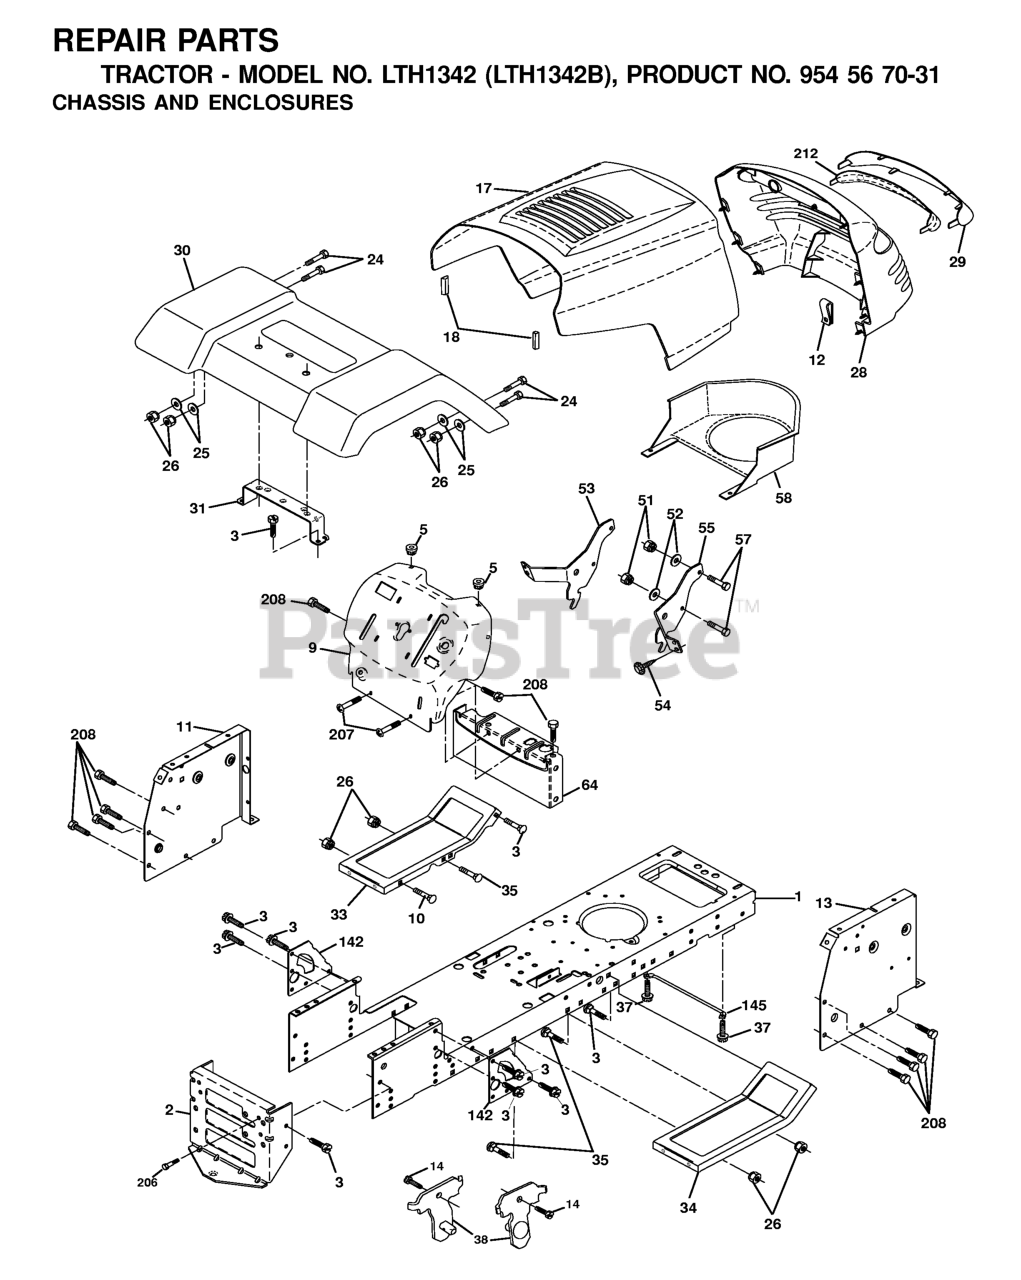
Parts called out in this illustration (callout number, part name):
1	CHASSIS STAMPING
2	DRAWBAR, 12GA
3	SCREW 3/8-16X3/4
5	BUMPER.RUBBER.HOOD
9	DASH
10	BOLT D
11	PANEL DASH LH
13	PANEL DASH RH
17	HOOD ASM.
18	BUMPER HOOD T
25	WASHER
26	NUT
28	GRILLE/LENS ASM.
29	LENS P/L
30	FENDER
31	BRACKET FENDER
33	FOOT REST LH
34	FOOTREST RH
37	Screw 5/16-18 x 1/2 Hex, Self Tapping 5/16-18 x 1/2
38	BRACKET
51	LOCKNUT.NYLOC.1/4-20
53	BRACKET.GRILLE.LH
54	SCREW.HEX.WS.HD.8-18 X 7/8
57	BOLT
58	AIR DUCT P/L/LT
64	DASH LOWER
142	PLATE
145	ROD PIVOT CHASSIS/HOOD
206	SHOULDER BOLT 5/16-18TT
207	SCREW, 5/16-18 X 1/2
208	SCREW 3/8-16X1/2
212	REPL BY 532 1745-03
